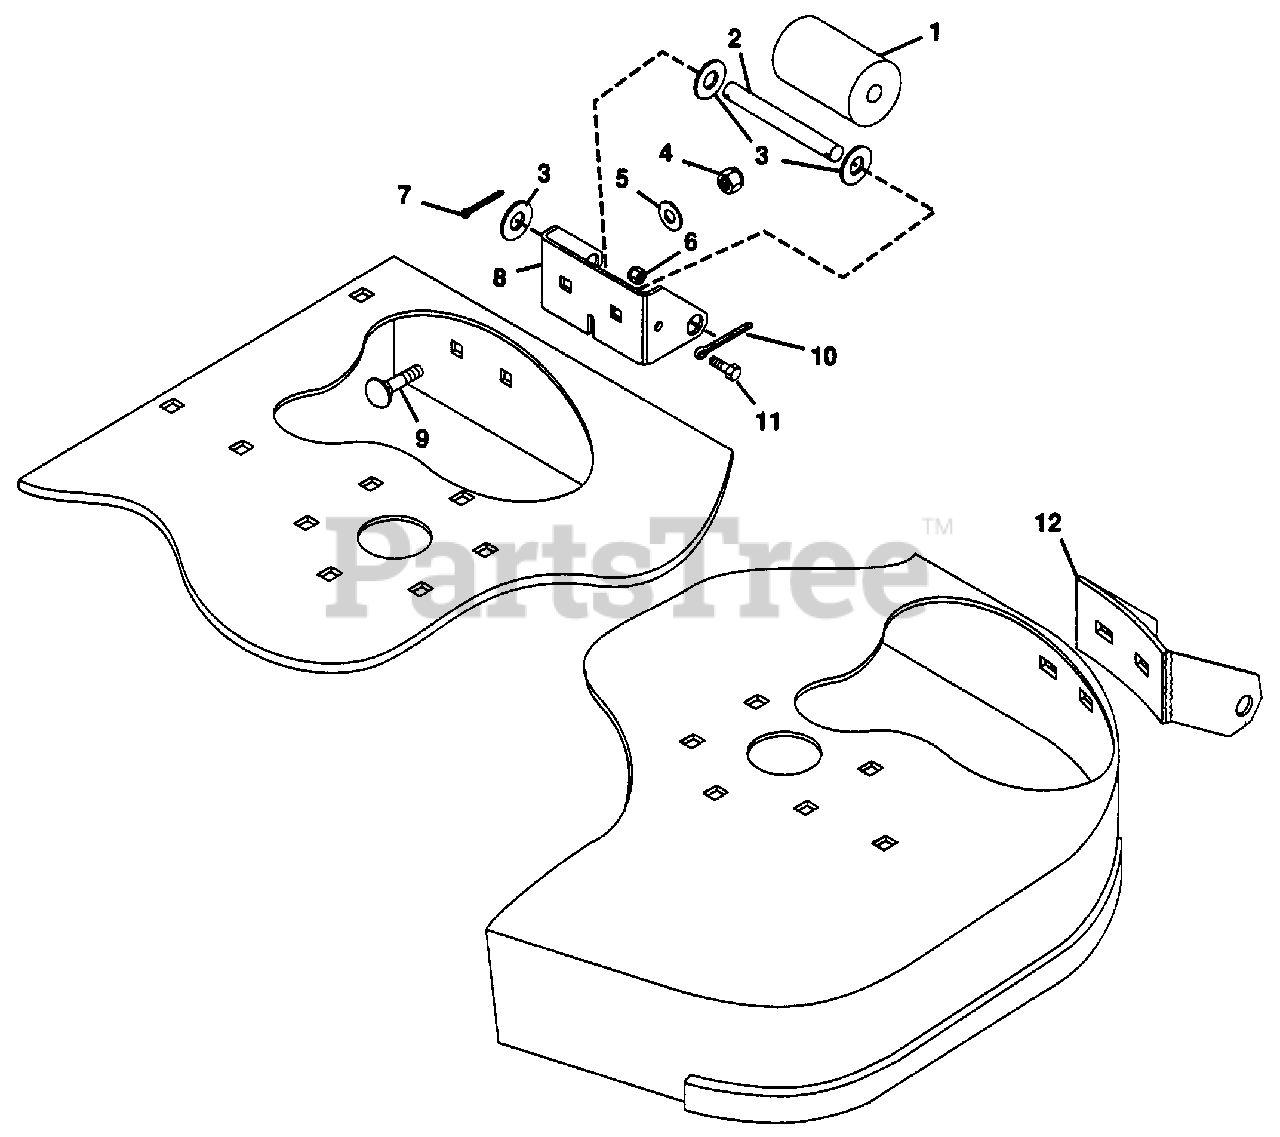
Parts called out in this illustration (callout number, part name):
1	Roller, Gage
2	Rod
3	Washer, Flat .656x1.312x.095
4	Nut, Lock 3/8-16
5	Washer, Flat .406x.812x.065
6	Nut, Hex 1/4-20
7	Pin, Cotter .25x1.00
8	Bracket, Roller
9	Bolt, 3/8-16x1.00 Rd Hd Sq Nk
10	Pin, Cotter .25x2.00
11	Bolt, Hex 1/4-20x.75
12	Weldment, Roller Bracket
